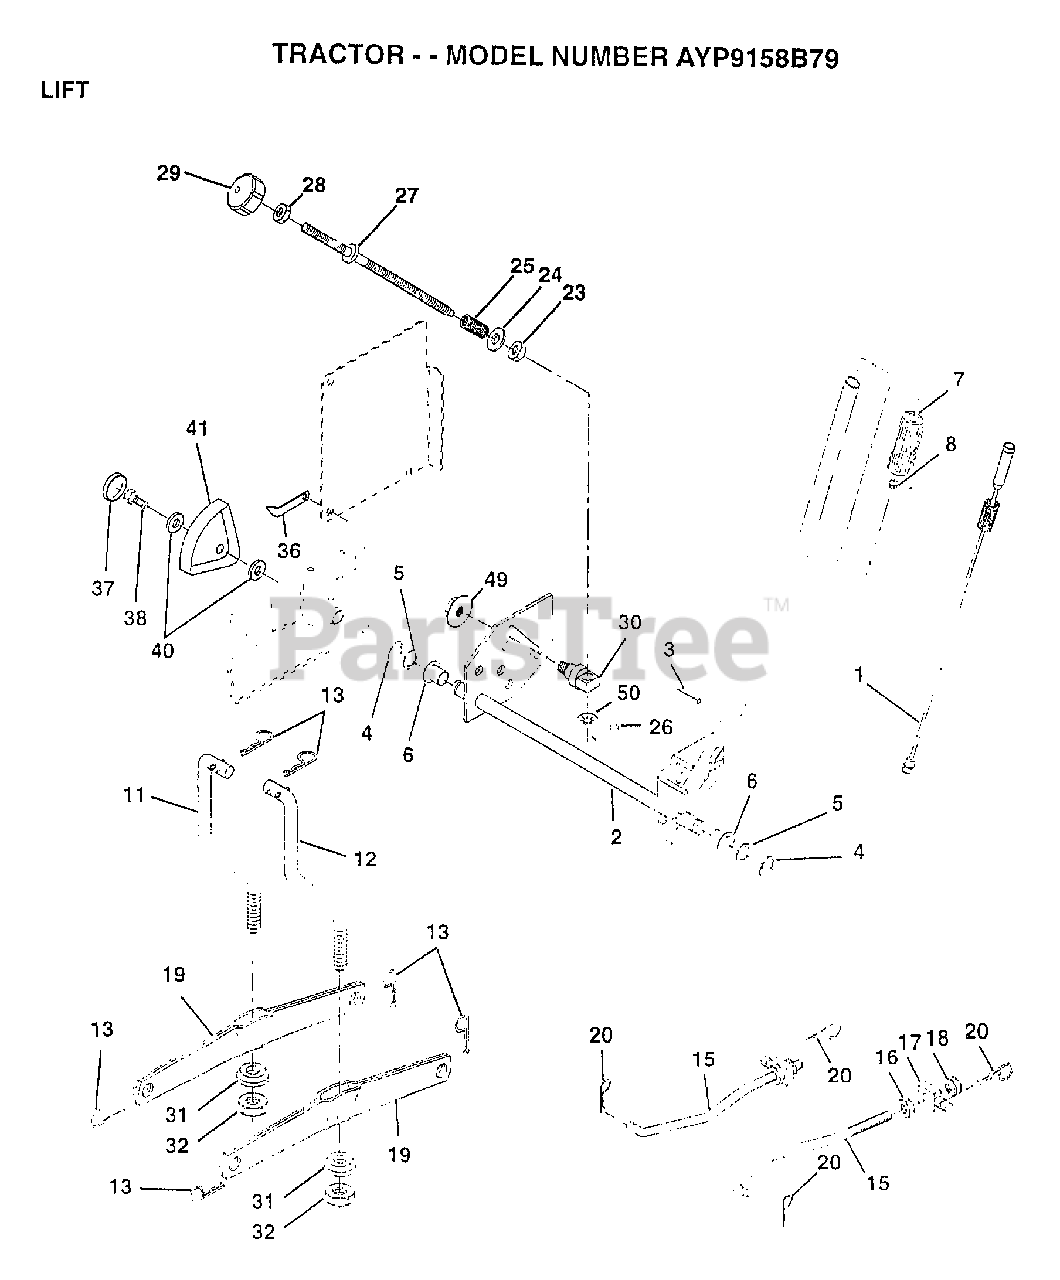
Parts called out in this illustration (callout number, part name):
1	WIRE ASM W.SPRING
2	"SHAFT ASM LIFT,RH"
3	PIN-GROOVE LT
5	WASHER
6	NYLON BEARING
7	GRIP HANDLE
15	LINK.FRONT
16	NUT
17	TRUNION
18	NUT.LK.W/WSH.1/2.
19	ARM SUSP REAR
20	RETAINER.SPRING
23	NUT T
24	WASHER
25	SPRING T
28	NUT
29	KNOB INF 3/8-16
30	TRUNNION
31	BEARING PVT LH
32	NUT.CROWNLOCK.3/8
36	POINTER-INDICAT
37	"PLUG,HOLE"
38	SCREW
40	WASHER
41	HEIGHT INDICATOR
49	NUT.HXFLG.LOCK.
50	NUT PUSH M
